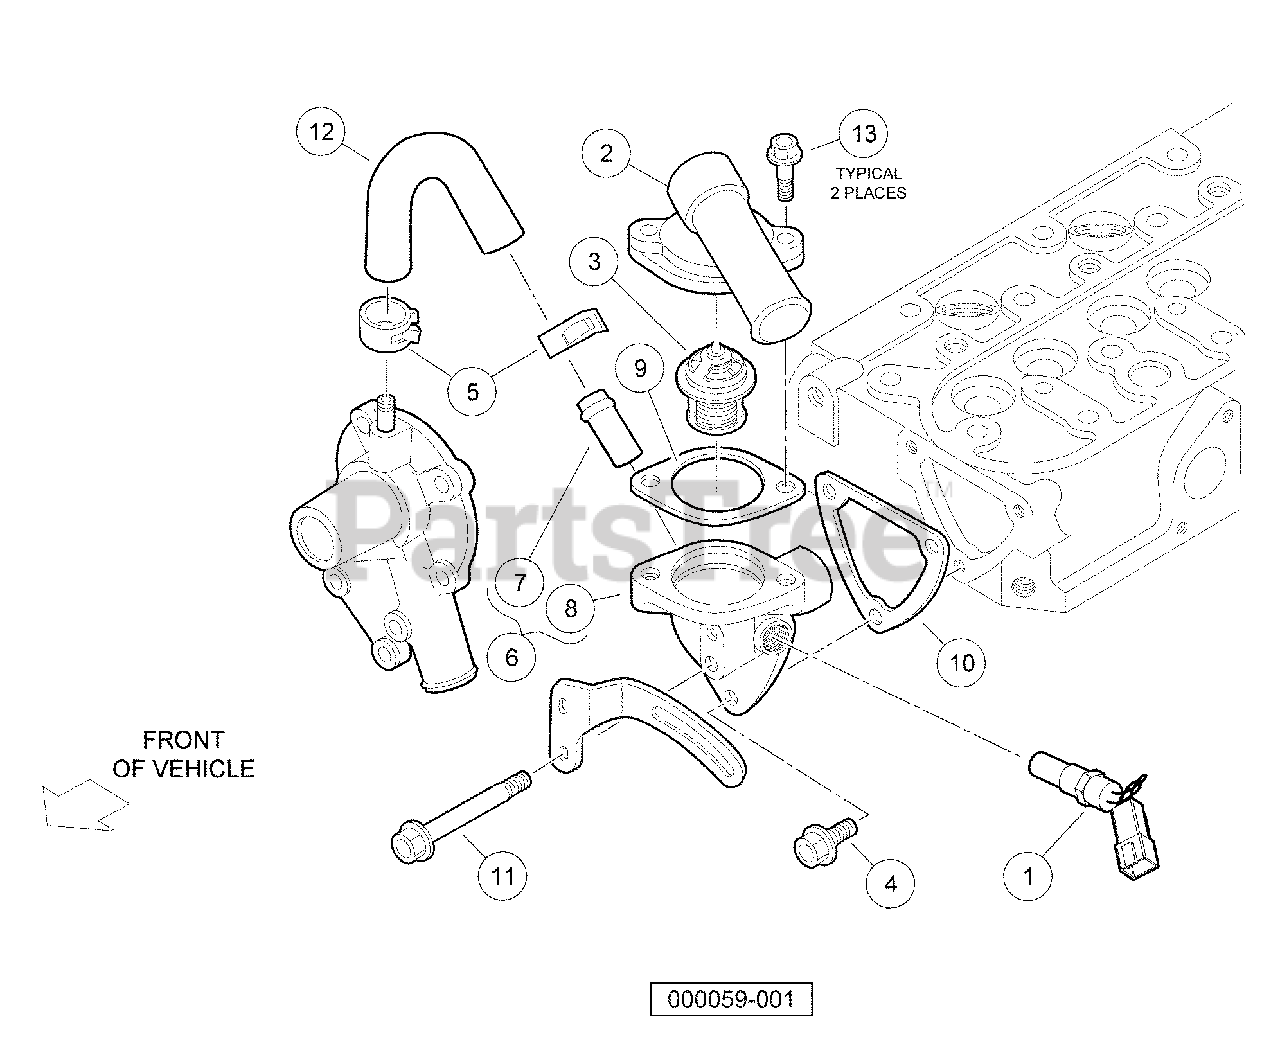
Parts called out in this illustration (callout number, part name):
1	Sensor, Coolant Temp
2	Cover, Thermostat
3	Assy, Thermostat
4	Bolt, M6 X 1 X 20
5	Band, Pipe
6	Flange, Water
7	Pipe, Water Return, D722
8	Flange, Water
9	Gasket, Thermostat
10	Gasket, Water Flange
11	Bolt, Alt, D722, Stay Lower
12	Pipe, Water Return, D722
13	Bolt, D722, Thermostat Cover
